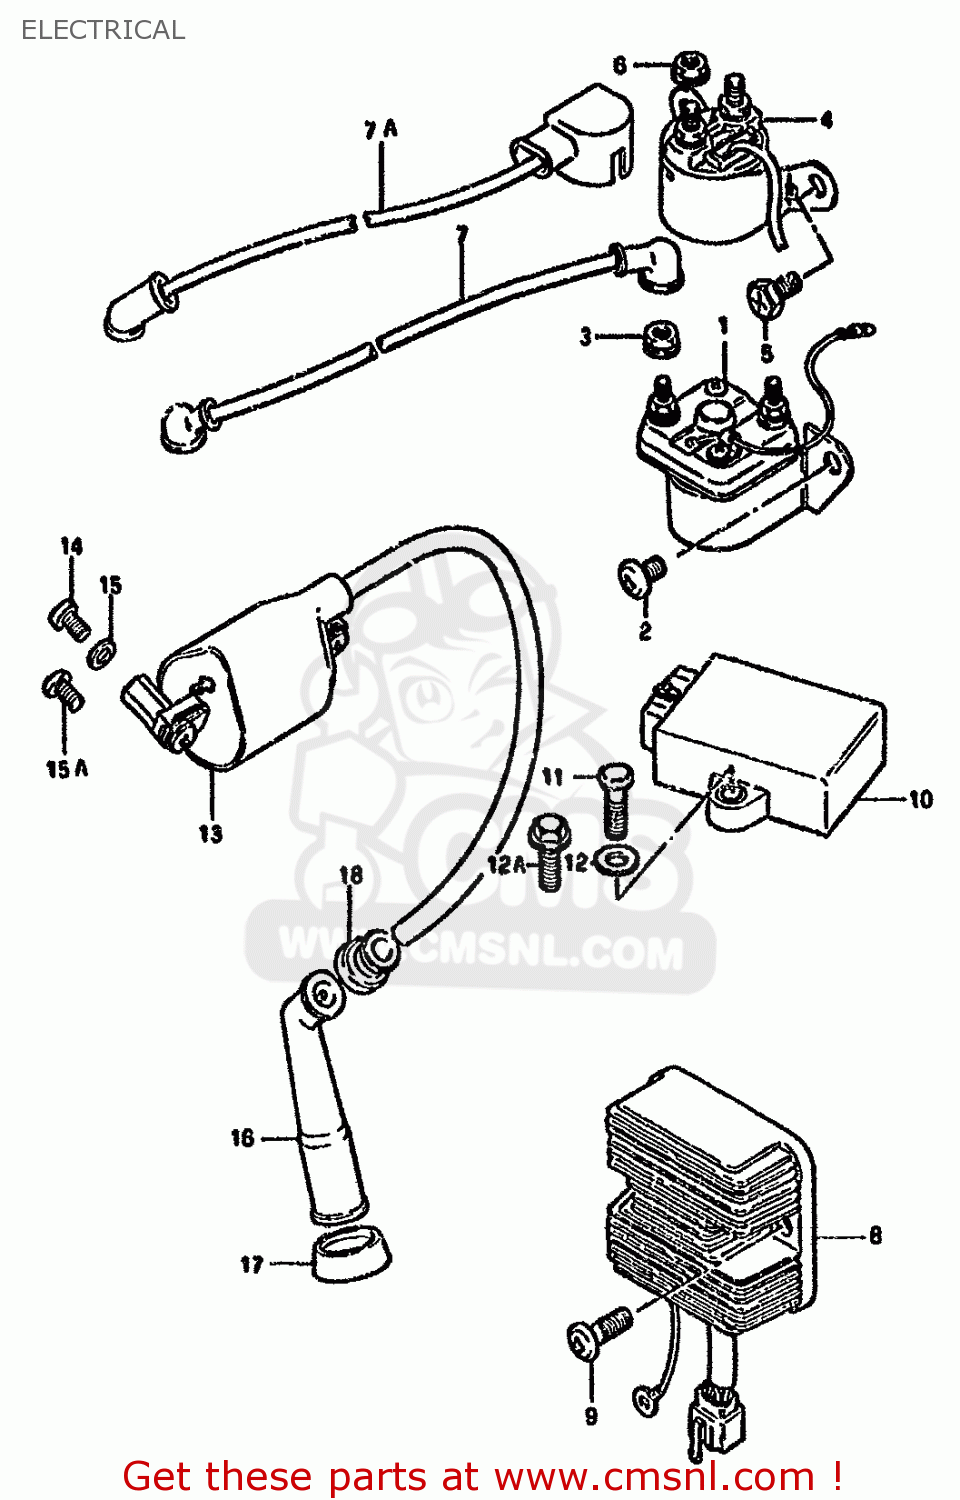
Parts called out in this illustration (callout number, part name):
1	RELAY ASSY,STARTING MOTOR
2	SCREW
3	NUT
4	RELAY ASSY,STARTING MOTOR
5	SCREW(6X10)
6	NUT
7	WIRE,STARTER MOTOR
7A	WIRE,STRT.LEAD
8	RECTIFIER ASSY
9	BOLT(6X20)
10	IGNITOR UNIT
11	BOLT
12	WASHER
12A	BOLT
13	COIL ASSY,IGNITION
14	SCREW
15	WASHER
15A	SCREW
16	CAP ASSY,SPARK PLUG
17	SEAL,SPARK PLUG CAP
18	SEAL,HIGH TENSION CORD
